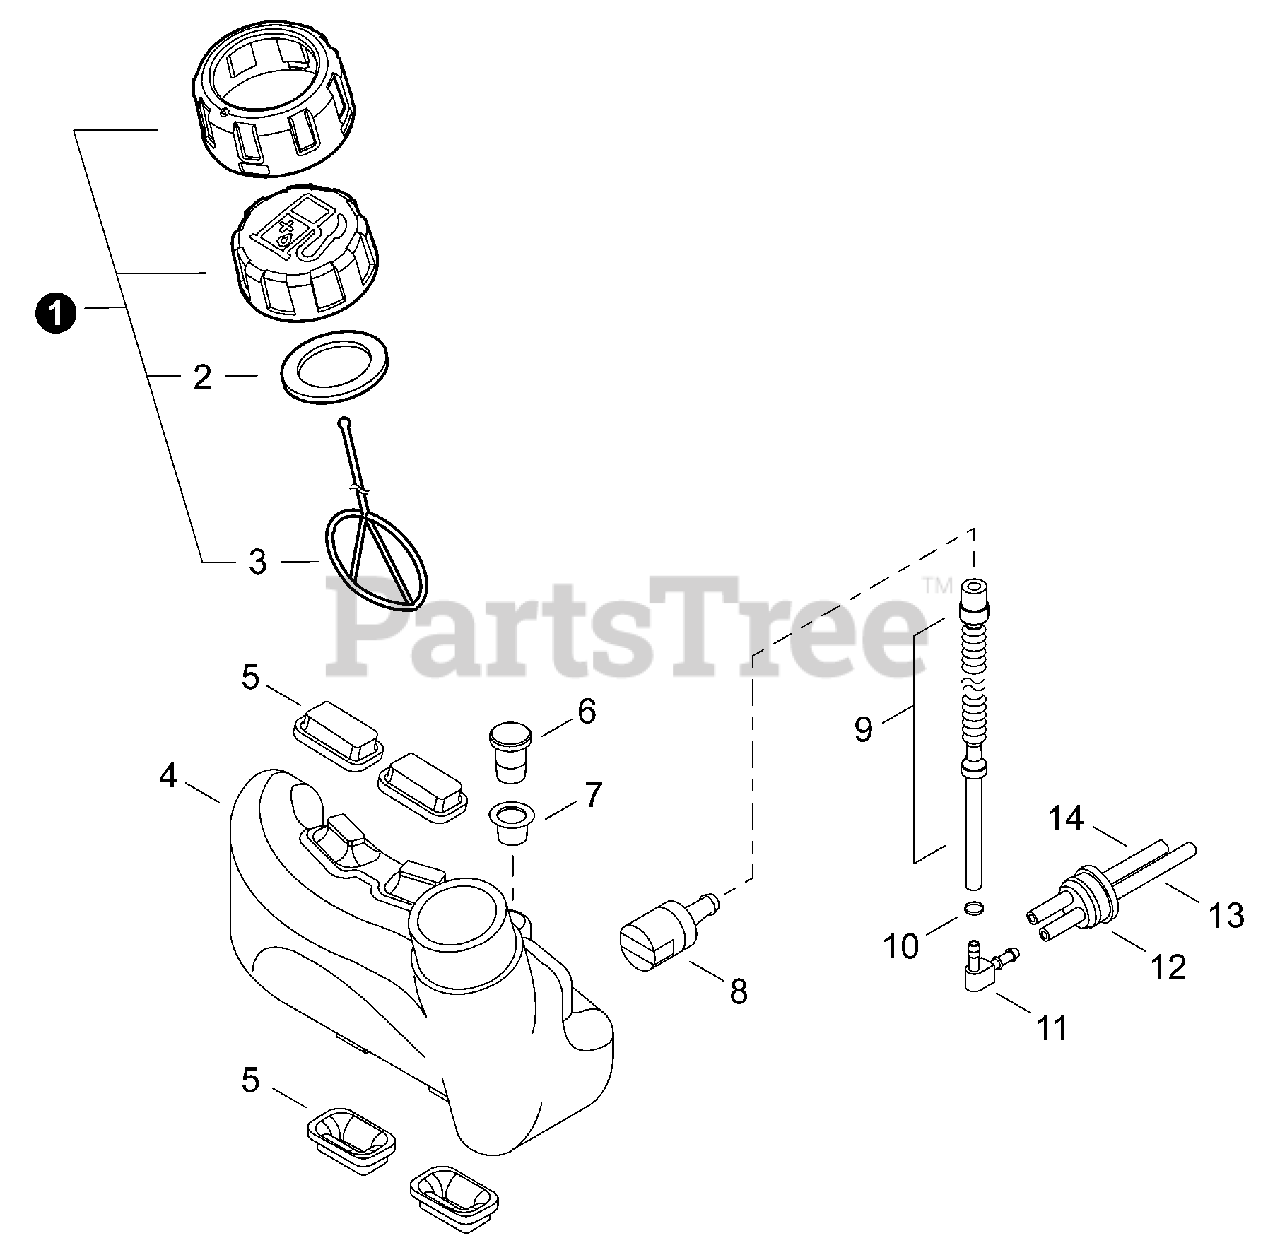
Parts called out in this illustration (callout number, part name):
1	CAP ASSY, FUEL
2	GASKET, FUEL CAP
3	CONNECTOR, CAP L= 123
4	TANK, FUEL
5	CUSHION
6	VENT ASSY
7	GROMMET, FUEL
8	FILTER, FUEL
9	PIPE, FUEL 125MM
10	CLIP 6.5MM
11	CONNECTOR, PIPE 5.4
12	GROMMET, FUEL
13	PIPE, FUEL 3×5×83
14	PIPE, FUEL 3×6×85 CLEAR
